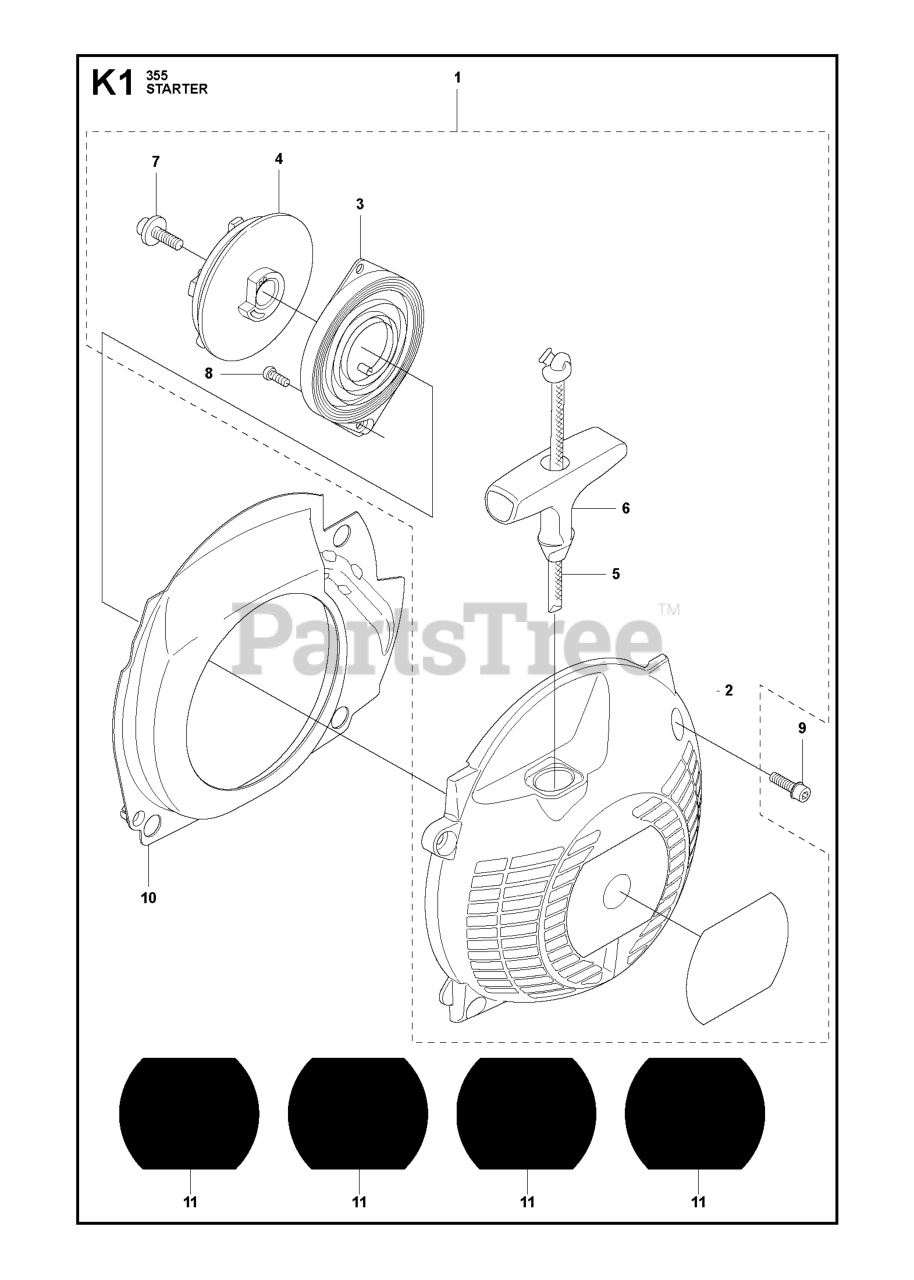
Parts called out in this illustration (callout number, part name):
1	STARTER
2	STARTER HOUSING
3	RECOIL SPRING
4	STARTER PULLEY
5	STARTER ROPE
10	AIR CONDUCTOR
11	LABEL
